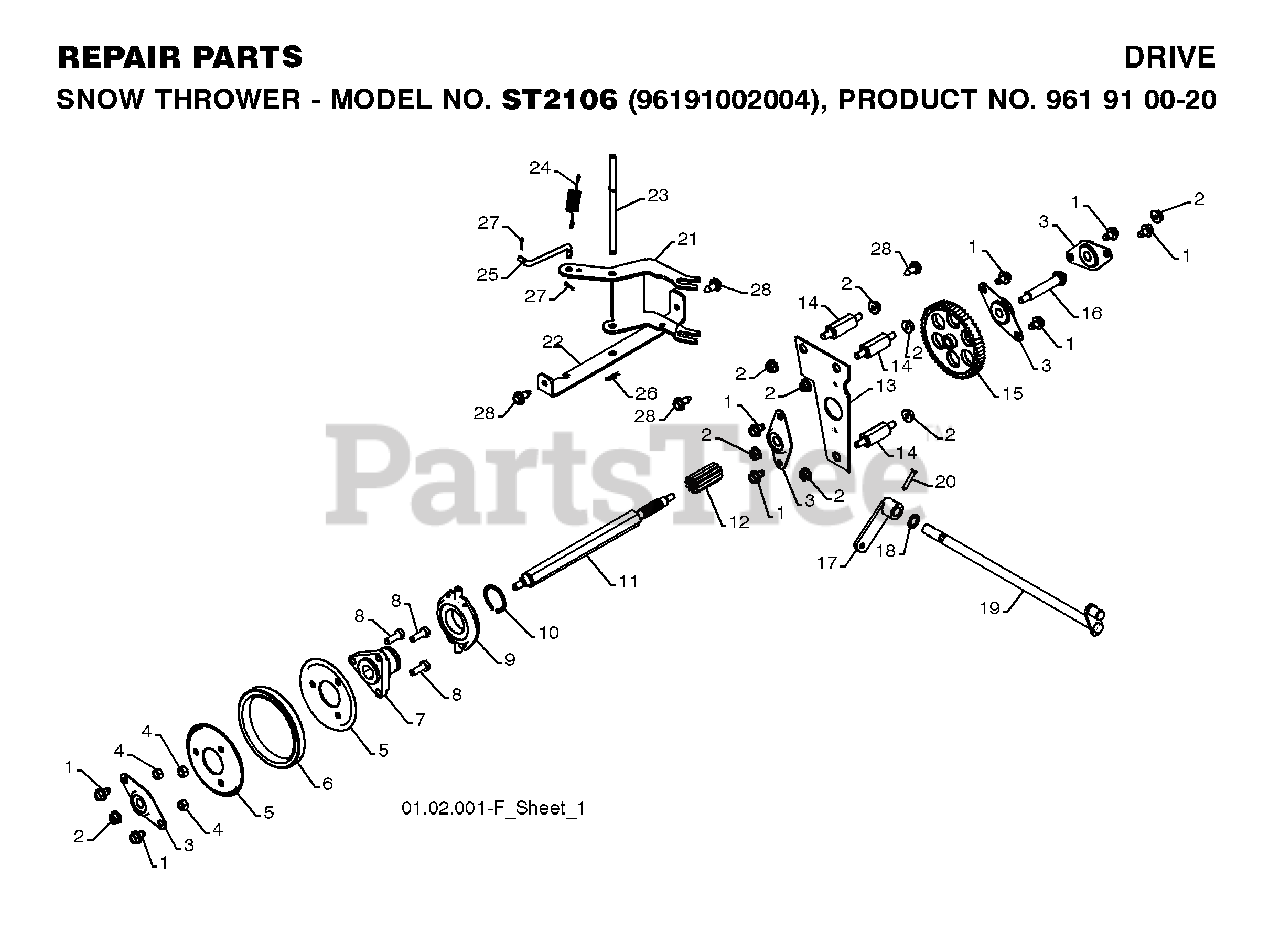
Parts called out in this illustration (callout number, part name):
2	NUT, LOCK 5/16-18
3	BEARING, FLANGE
4	NUT.CENTERLOCK.5/16-
5	PLATE.RUBBER.WHEEL
6	RING, RUBBER WHEEL
7	HUB, RUBBER WHEEL
9	TRUNNION BEARING ASSY
10	RETAINING RING
11	SHAFT.HEX.LONG
12	GEAR, PINION
13	AUXILLARY PLATE
14	SPACER, PLATE
15	GEAR, INTERMEDIATE
16	SHAFT, AUXILIARY
17	ARM, AUGER CONTROL
18	THRUST WASHER
19	SHAFT, AUGER CONTROL
20	CLEVIS PIN
21	LEVER, SPEED CONTROL
22	BRACKET, PIVOT, SHIFT
23	PIN, PIVOT
24	SPRING, BIAS
25	LINK, SPEED CONTROL
26	RETAINER CLIP PM
27	RETAINER CLIP
28	SELF-TAPPING SCREW 5/16-18X3/4
